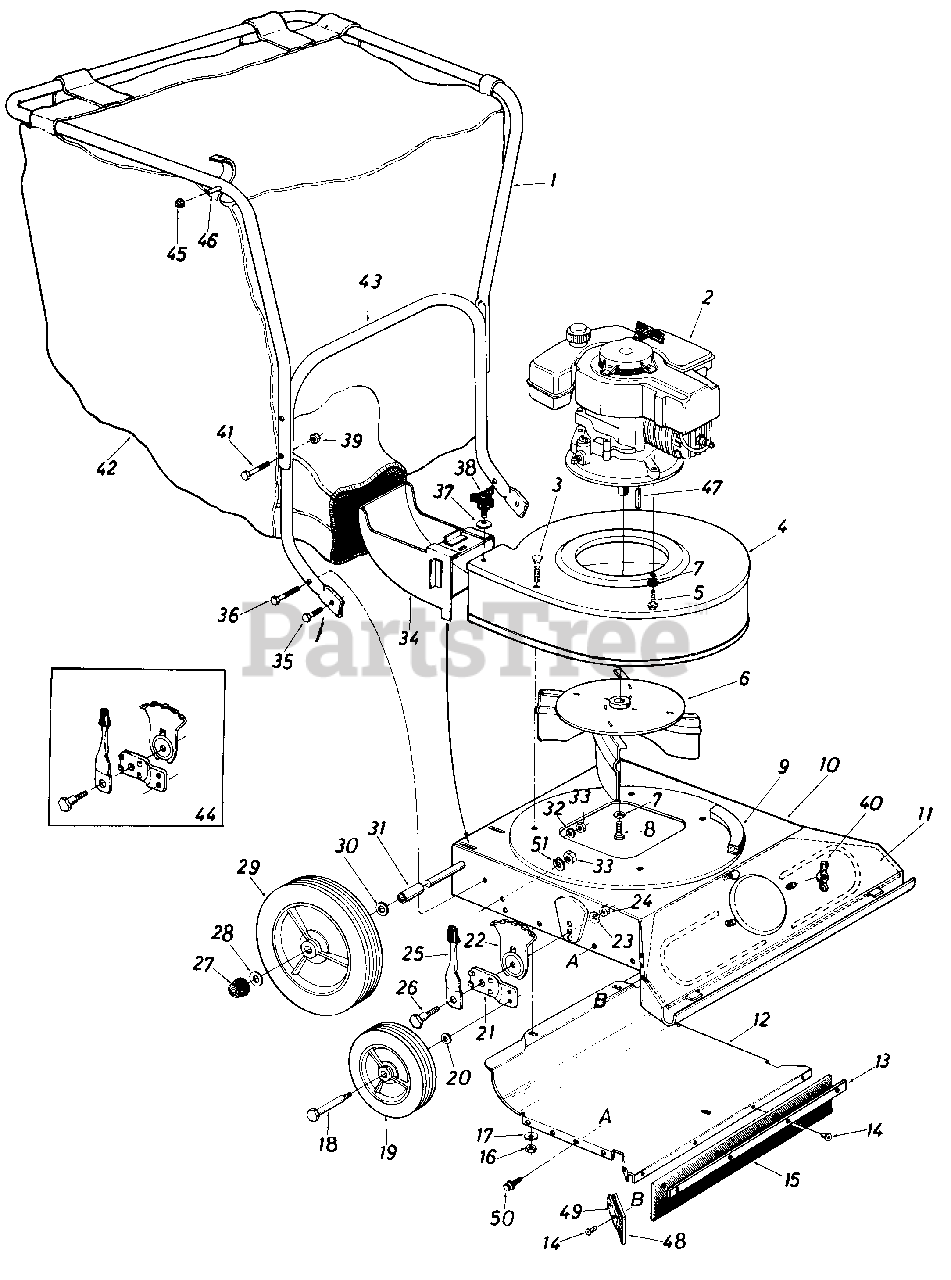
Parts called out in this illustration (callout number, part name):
1	Upper Handle (Painted)
2	Engine
3	Carriage Bolt 5/16-18 x .62" Lg.
4	Blower Housing Ass'y.
5	Hex Tap Scr. 3/8-16 x 1.00" Lg.
6	Impeller Ass'y.
7	L.-Wash. 3/8" I.D.
8	Hex Bolt 3/8 24 x 1.0" Lg. w/Patch
9	P.V.C. Foam Strip (4-Pcs. 12" Lg. )
10	Vacuum Deck Ass'y.
11	Front Baffle Ass'y.
12	Lower Baffle Ass'y.
13	Wiper Retaining Strip
14	Pop Rivet.188" Dia.
15	Nozzle Wiper Rear
16	Hex Nut 5/16-18 Thd.
17	Bell.-Wash. .34" I.D. x.87" O.D.
18	Shld. Bolt 1/2" Dia. x 1.45" Lg. (3/8-16)
19	Wheel Ass'y. Comp. 8 x 1.75"-Front
20	Bell.-Wash. .39" I.D. x 1.12" 0. D.
21	Wheel Pivot Bar
22	Index Plate
23	Bell.-Wash. .39" I.D. x 1.12" 0. D.
24	Hex Nut3/8-16Thd.
25	Spring Lever Ass'y. w/Knob
26	Shoulder Bolt .500" x 7/16" Lg. (3/8-16)
27	Push Cap .50" Rod (Black)
28	Fl.-Wash. 1/2" I.D. x 1.0" O.D. x .06
29	Wheel Ass'y. Comp. 10 x 1.75"-Rear
30	Fl.-Wash. 1/2" I.D. x 1.0" O.D. x .06
31	Wheel Spacer 1/2" I.D. x 15/16 Lg.
32	Bell.-Wash. .39" I.D. x 1.12" 0. D.
33	Hex Nut 3/8-16 Thd.
34	Air Duct Ass'y.
35	HexBolt3/8-16x.75" Lg.
36	Hex Bolt 3/8-16 x 1.50" Lg.
37	Bell.-Wash. .34" I.D. x .87" O.D
38	Thumb Scr. 5/16-18 x .75" Lg.
39	HexCent. L.-Nut 1/4-20Thd.
40	Wing Nut 1/4-20 (Plastic)
41	Hex Bolt 1/4-20 x 1.75" Lg.
42	Vacuum Bag (6.6 Bushel)
43	Lower Handle (Painted)
44	Height AdjusterAss'y. Comp.-R.H.
45	Push Speed Nut .25" Dia.
46	Stud Pin .250" Dia. x 1.75" Lg.
47	Sq. Key 3/16 x 3/16 x 1.00"Lg
48	Nozzle Wiper Side
49	Wiper Retaining Strip
50	Hex-Wash. Hd. " F" Tap Scr. #10
51	L-Wash. 3/8" I.D.
